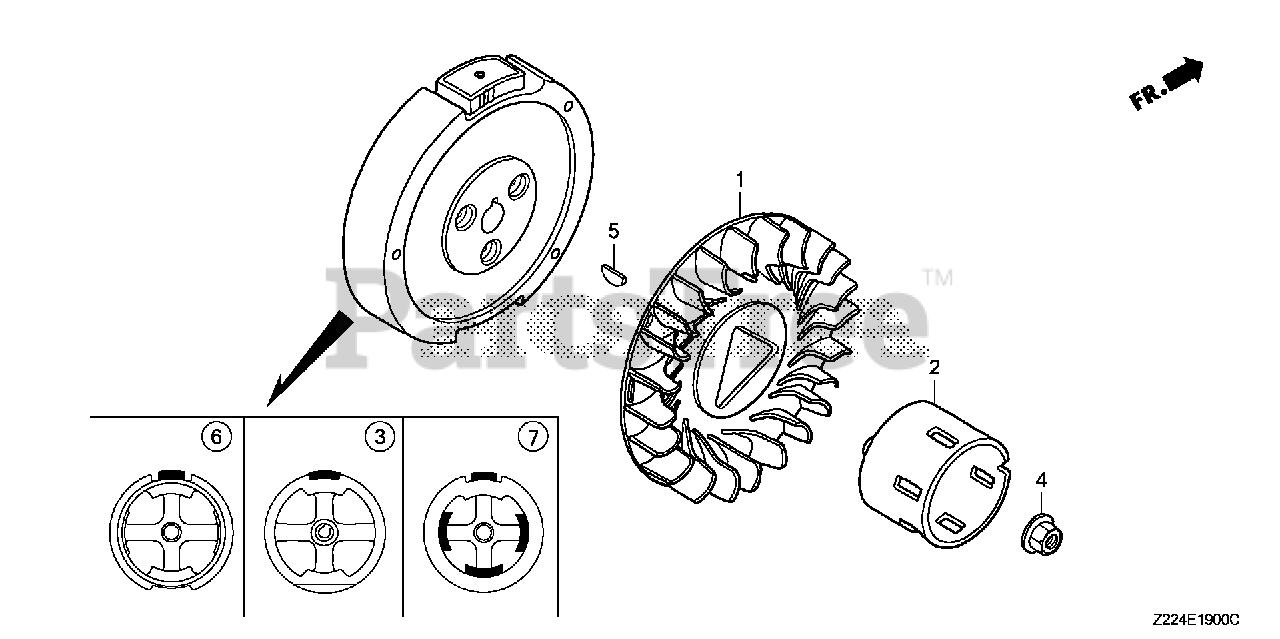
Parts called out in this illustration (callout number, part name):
1	FAN, COOLING
2	PULLEY, STARTER
4	NUT, SPECIAL (16MM) (1)
5	KEY, SPECIAL WOODRUFF (25X18)
